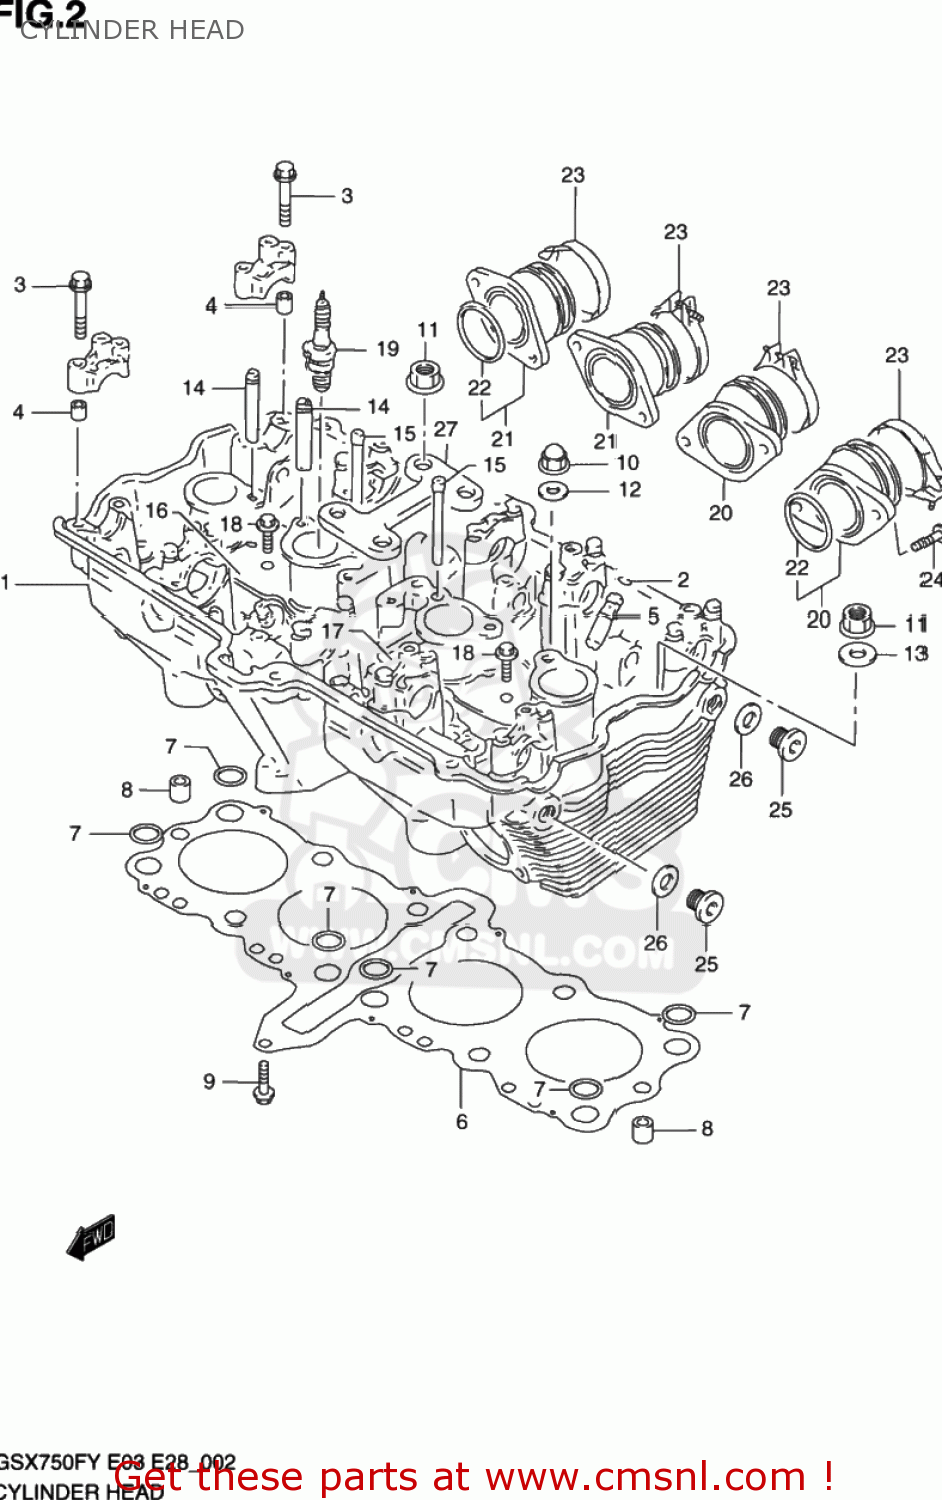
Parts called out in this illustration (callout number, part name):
1	HEAD ASSY,CYLINDER
2	RING,SNAP
3	BOLT(6X39)
4	PIN(6.2X8X11)
5	GUIDE,VALVE
6	GASKET,CYLINDER HEAD (NAS)
7	O RING,HEAD GASKET
8	PIN
9	BOLT
10	NUT
11	NUT
12	GASKET(10.2X20X2).3 (NAS)
13	WASHER (10.5X22X2.3)
14	PIPE,OIL NO.1
15	PIPE,OIL NO.3
16	PLATE,OIL PIPE,R
17	PLATE,OIL PIPE,L
18	BOLT
19	PLUG,SPARK(CR9EK)
20	PIPE ASSY,INTAKE NO.1
21	PIPE ASSY,INTAKE NO.3
22	O RING(D:2.4,ID:41.7)
23	CLAMP
24	BOLT MAGNETO S
25	PLUG
26	GASKET(13.8X18.8X4.8) (NAS)
27	PLATE,HEAD REINF
